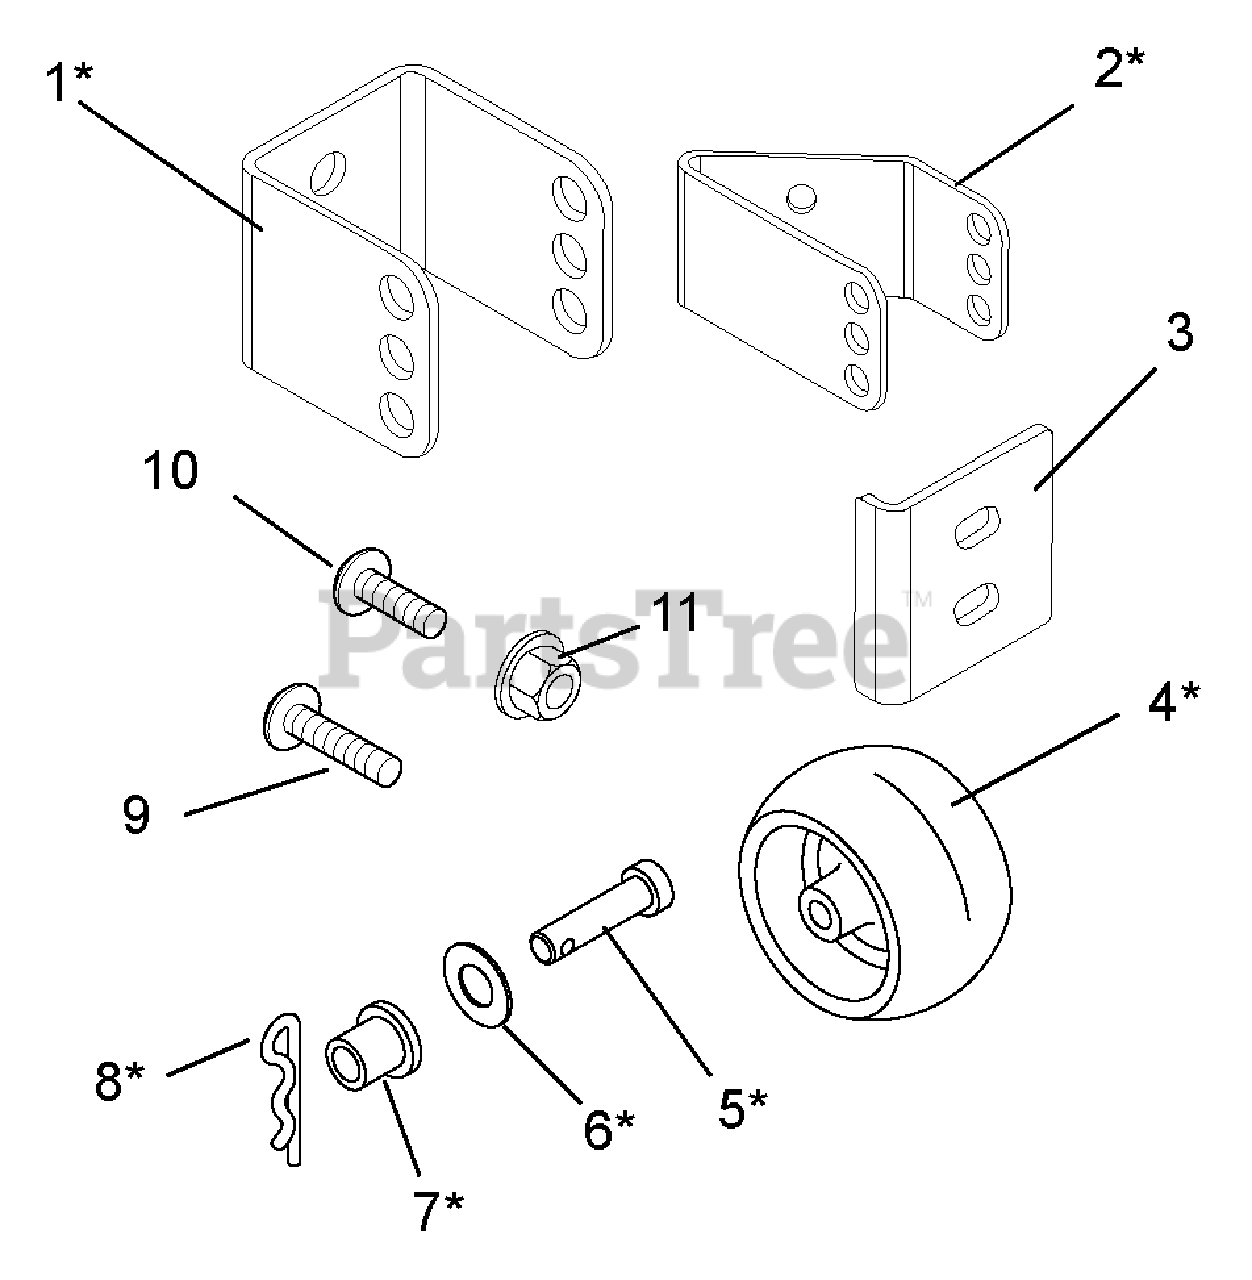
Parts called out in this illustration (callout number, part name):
1	Antiscalp Bracket
2	Antiscalp Bracket
3	Filler Bracket
4	Roller
5	Clevis Pin, 3/8 x 3-1/4
6	Plastic Washer, 25/64 x 7/8 x 1/16
7	Flange Bushing, 3/8 x 1/2 x 5/16 x 5/8
8	Hair Pin, 5/64 x 3/16 x 1-3/16
9	Button Head Socket Bolt, 3/8-16 x 1
10	Button Head Socket Bolt, 3/8-16 x 3/4
11	Top Locking Flange Nut, 3/8-16
